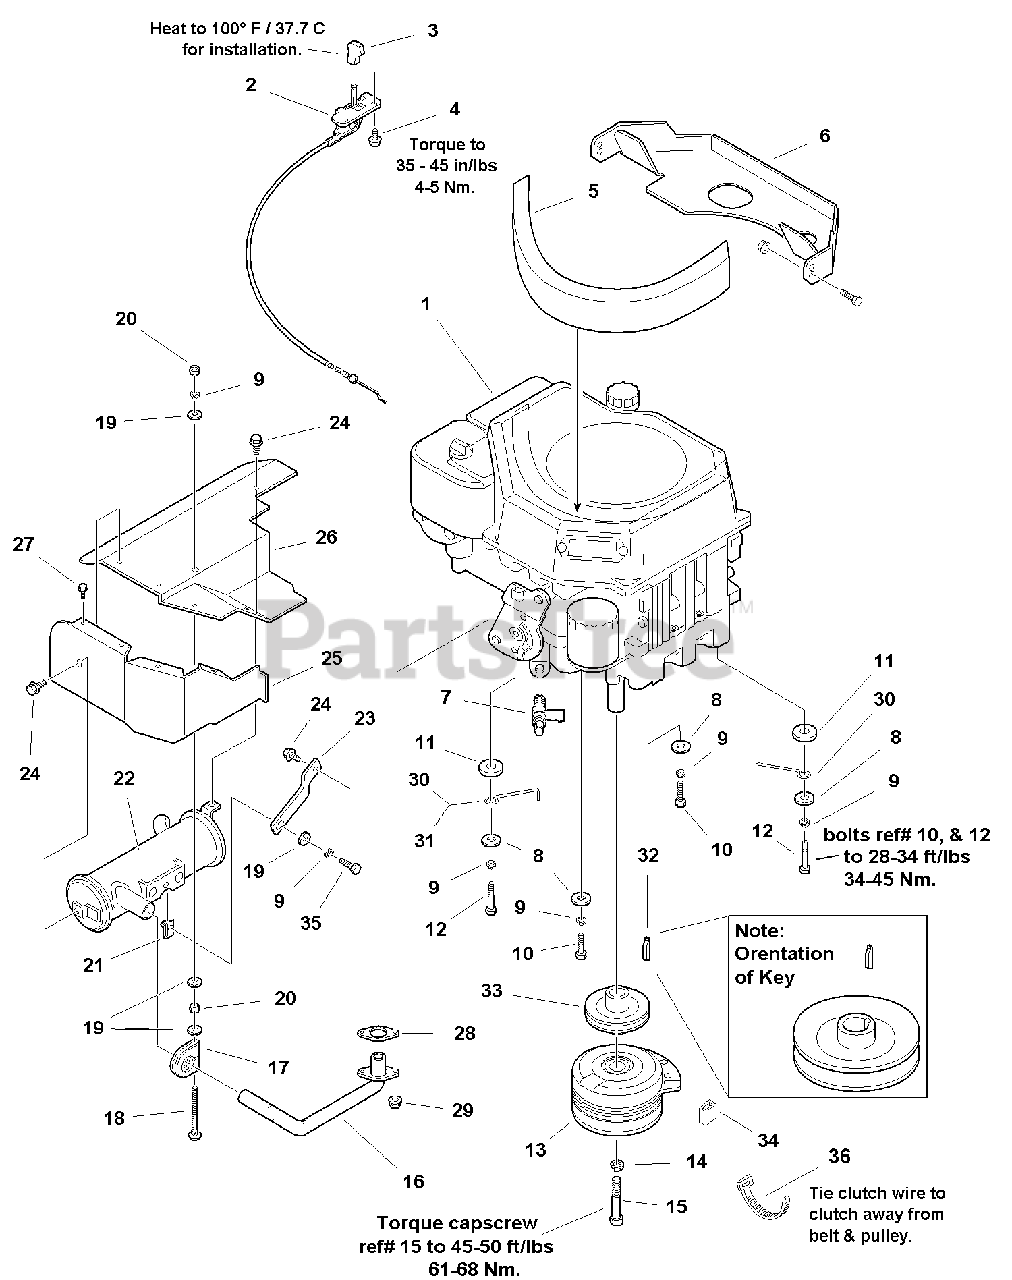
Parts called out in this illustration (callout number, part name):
2	THROTTLE CONTROL ASSEMBLY
3	KNOB, Throttle
4	SCREW, Plastite, 1/4-10 x 1/2
5	SEAL, Air Inlet
6	AIR DUCT
7	VALVE, Shut Off
8	WASHER, 5/16
9	LOCKWASHER, 5/16
10	CAPSCREW, Hex, #8 - 1.25 x 30mm
11	WASHER, Plain
12	CAPSCREW, Hex Head, M08 - 1.25 x 40mm
13	CLUTCH, Electric
14	LOCKWASHER, 7/16
15	CAPSCREW, Hex Head, 7/16-20 x 2-1/2
16	PIPE, Exhaust
17	CLAMP, Muffler
18	CARRIAGE BOLT, 5/16-18 x 3-1/4
19	WASHER, 5/16
20	NUT, Hex, 5/16-18
21	NUT, Speed, Lug Type, 5/16-18
22	MUFFLER ASSEMBLY
23	SUPPORT, Muffler
24	CAPSCREW, Hex Head, Taptite, 5/16-18 x 1/2
25	AIR DUCT, Bottom
26	SHIELD, Muffler
27	CAPSCREW, Hex Head, Thd. Form, #10-16 x 1/2
28	GASKET
29	NUT, Hex
30	BELT STOP (Hydro Models)
30	BELT STOP, Rear (Gear Models)
31	BELT STOP, Front (Gear Models)
32	KEY, Hi-Pro
33	PULLEY, Engine (Gear Models)
33	PULLEY, Engine (Hydro Models)
34	SLEEVE, Clutch Anchor
35	CAPSCREW, Hex Head, 5/16-18 x 1
36	TIE, Self Locking
